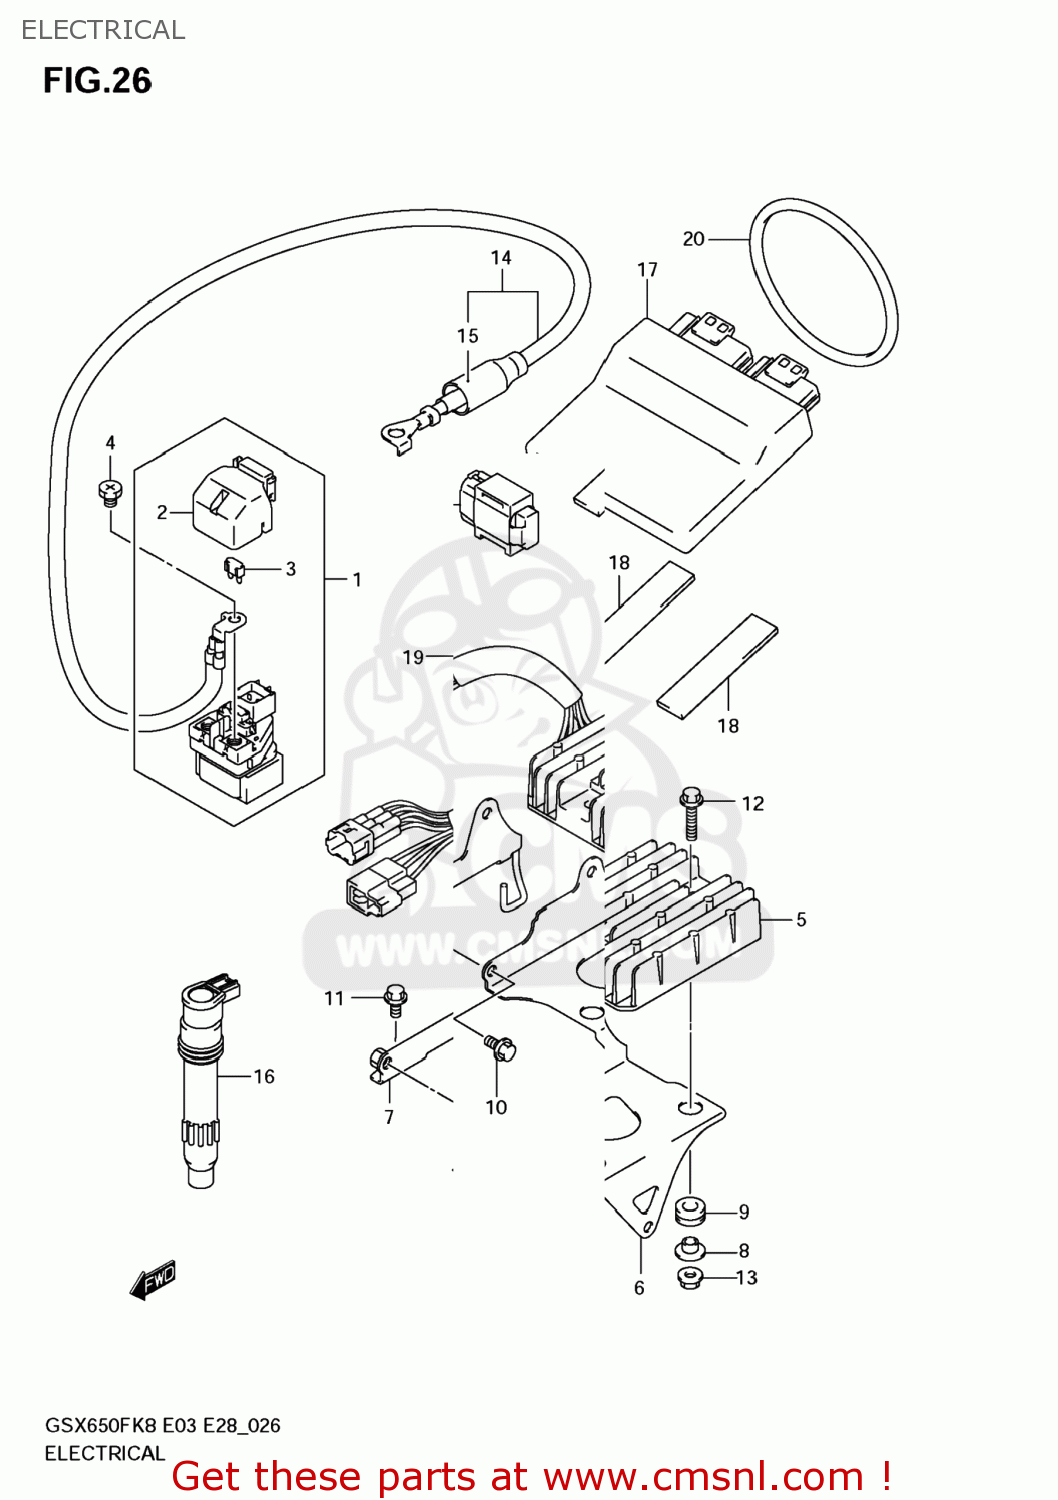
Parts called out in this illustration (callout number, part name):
1	RELAY ASSY,STARTING MOTOR
2	COVER
3	FUSE(30A)
4	SCREW(6X8)
5	RECTIFIER ASSY
6	BRACKET,RECT FTG NO.1
7	BRACKET,RECT FTG NO.2
8	SPACER(6.2X8.4X6.9)
9	CUSHION
10	BOLT
11	BOLT
12	BOLT
13	NUT
14	WIRE,STARTER MOTOR LEAD
15	CAP,STARTER MOTOR
16	COIL ASSY,IGNITION
17	CONTROL UNIT,FI
18	PROTECTOR(80X80X2)
19	SENSOR ASSY,FUEL CUT
20	O RING(D:3.53,ID:69.44)
